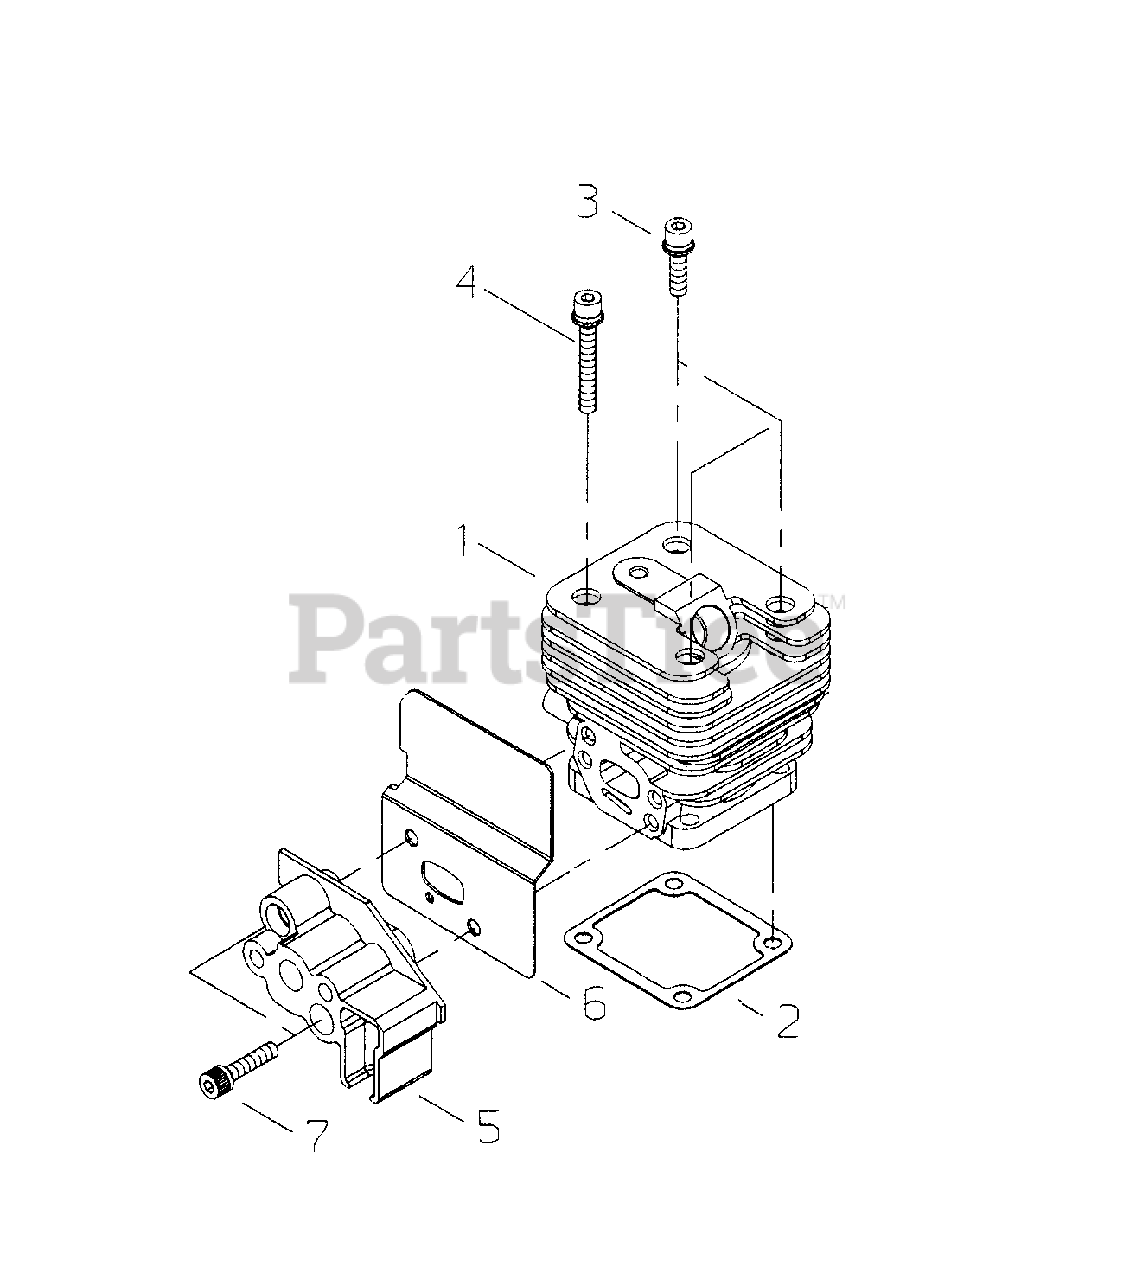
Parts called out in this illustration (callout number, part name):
1	CYLINDER
2	GASKET, CYLINDER
3	BOLT M5×16
4	BOLT M5×35
5	INSULATOR
6	HEAT SHIELD, INTAKE
7	BOLT M5×30
